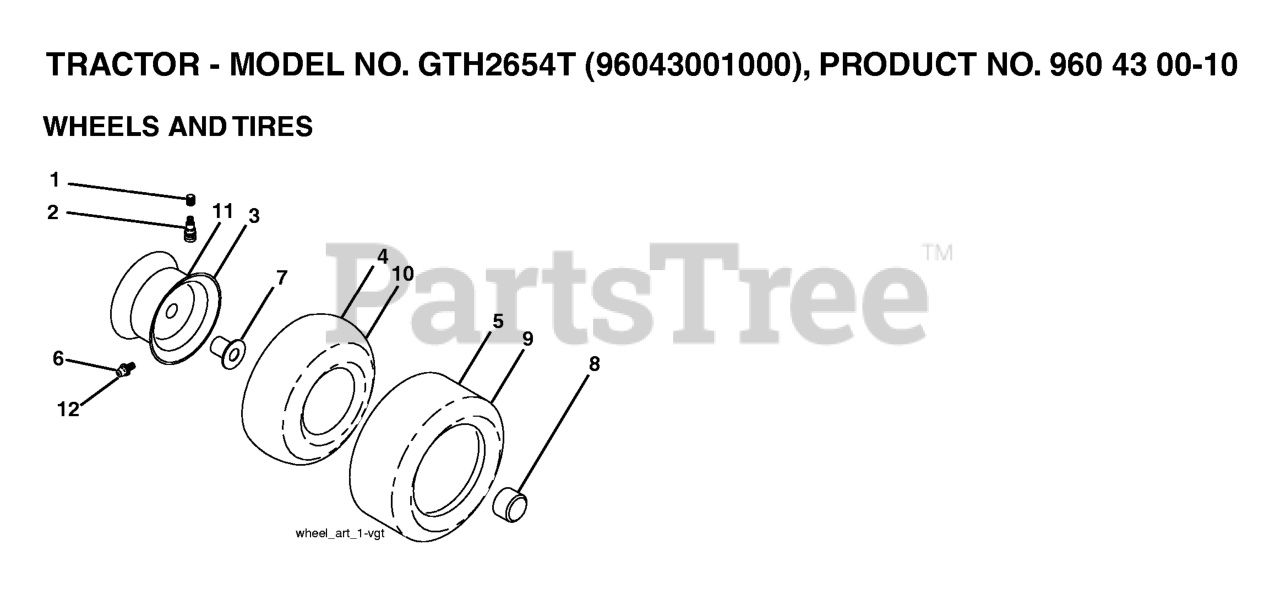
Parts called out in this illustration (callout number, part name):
2	VALVE STEM LT
3	RIM ASSEMBLY, FRONT
4	TUBE.16X6.5/7.5-8
5	TIRE HEAVY DUTY
6	FITTING LT.
7	BEARING.FLANGE
8	CAP, AXLE BLK
9	TIRE.22X9.50-12.TURF.SAVER.REA
10	TUBE.23X9.5-12
11	RIM.ASM.12".REAR.SILVER
12	FITTING, GREASE
